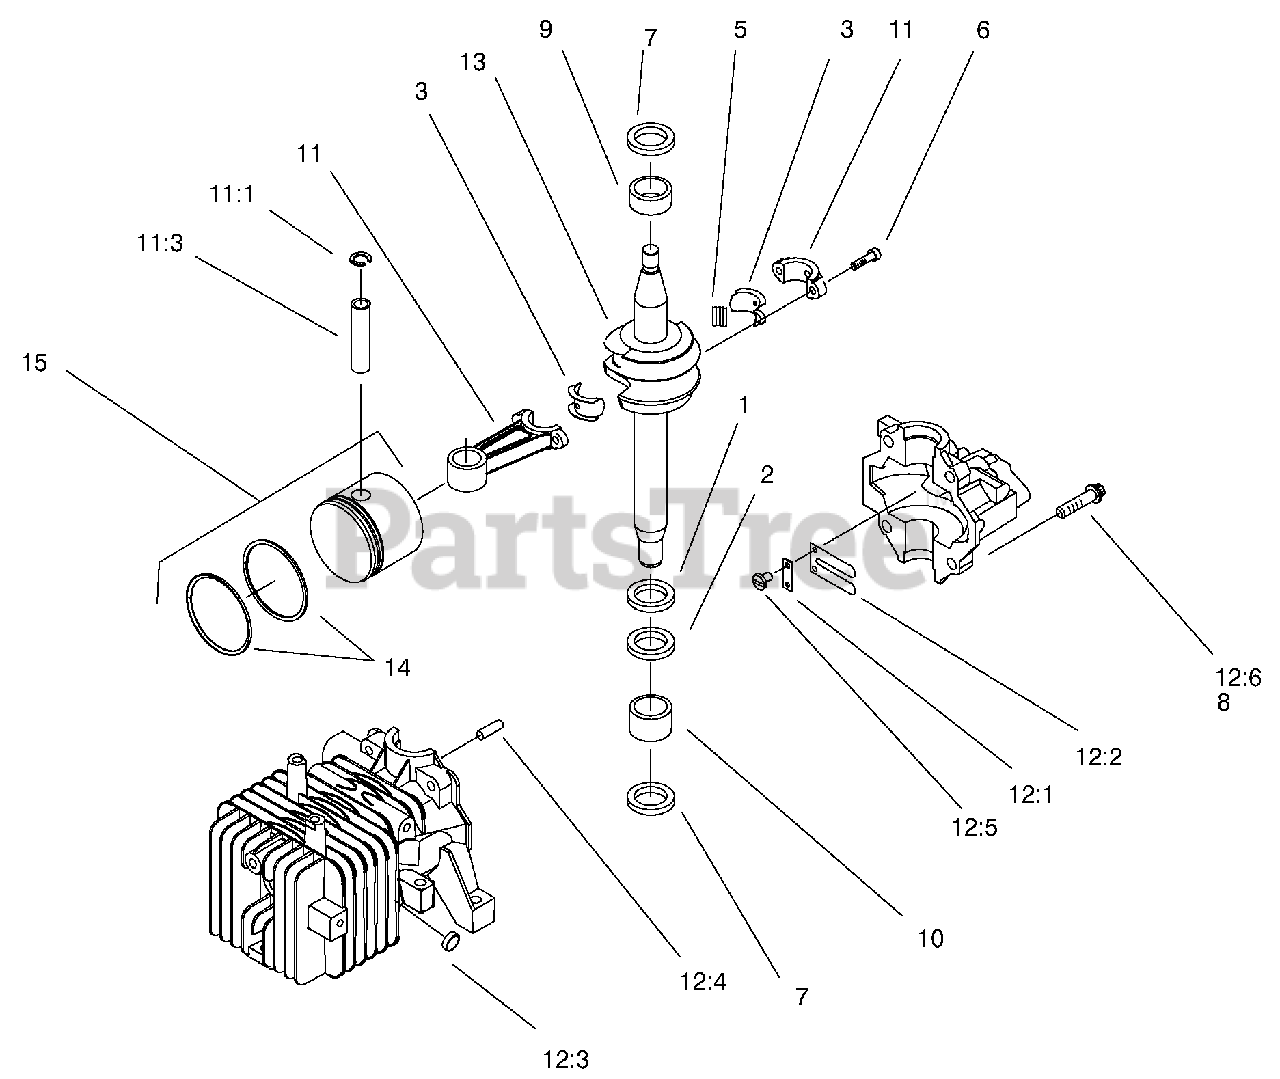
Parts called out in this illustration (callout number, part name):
1	Bearing-Thrust
2	Washer-Thrust
3	Liner ASM
5	Bearing-Needle
6	Screw-HSH
7	Seal-Oil
8	Screw-HWH
9	Bearing
10	Bearing
11	Connecting Rod ASM
11:1	Ring-Retaining
11:3	Wrist Pin
12	Cylinder & Crank Case ASM
12:1	Plate-Backup, Reed
12:2	Reed-Carburetor
12:3	Plug-Core
12:5	Screw-HH
12:6	Screw-HWH
13	Crankshaft
14	F-Ring Set
15	Piston & Ring
